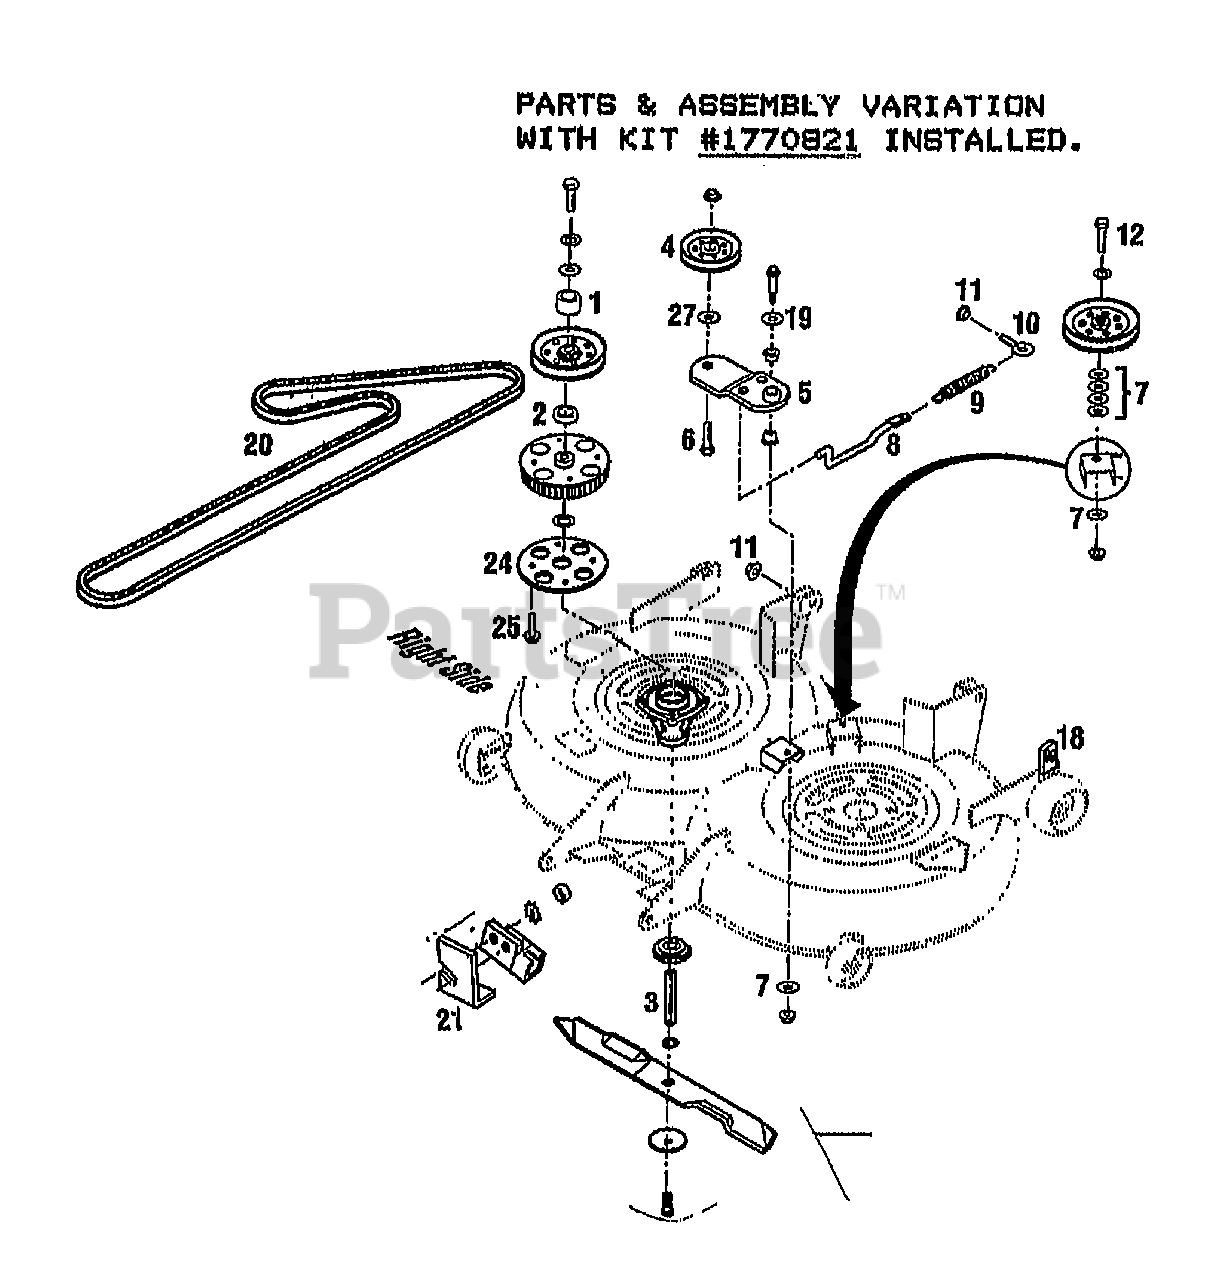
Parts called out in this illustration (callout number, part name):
1	SPACER-1.25X.77X.88
2	SPACER-1.25X.76X.50
3	SHAFT-LONG SPINDLE (RH)
4	PULLEY-IDLER
5	ASSM-IDLER ARM
6	SCR-HH 3/8-16X1.75 G5 ZP
7	WASHER-1.5X.375X.18 ZP
8	ROD-IDLER
9	SPRING
10	BOLT-EYE SC
11	NUT-HFLK 5/16-18 ZP
12	SCR-HH 3/8-16X2.50
18	LEVER-GAGE WHEEL ADJUST
21	BRACKET-SWITCH
24	PLATE-SPROCKET
25	SCR 1/4-20.75 TRI-PLASK
27	WASHER-.986X.437X.083 ZP
